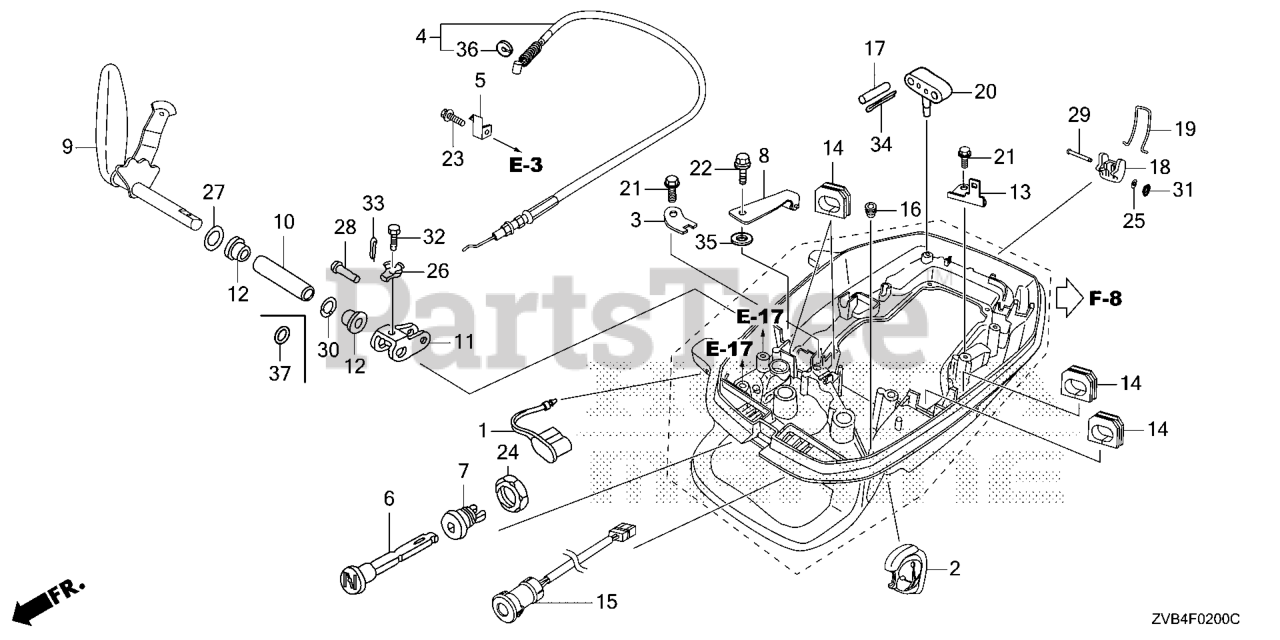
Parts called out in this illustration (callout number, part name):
2	GROMMET, THROTTLE CABLE
3	HOLDER, CABLE
4	CABLE COMP
5	BRACKET, CABLE
6	KNOB, CHOKE
7	GUIDE, CHOKE KNOB
8	SPRING, CLICK
9	SHAFT, SHIFT
9	SHAFT, SHIFT (NOT AVAILABLE)
10	COLLAR, SHIFT SHAFT
11	ARM, SHIFT
12	BUSH, SHAFT (NOT AVAILABLE)
13	BRACKET, CONNECTOR A
14	GROMMET, WIRE
15	LAMP ASSY., INDICATOR
16	GROMMET A, CASE (LOWER)
17	PIN, SHEAR
18	LEVER, FASTENER
19	WIRE, FASTENER (3.2)
20	HOLDER, PARTS
21	BOLT, FLANGE (6X14) (CT200)
22	BOLT, FLANGE (6X12) (CT200)
23	BOLT, FLANGE (6X12)
24	NUT, HEX. (16MM)
25	WASHER, PLAIN (5MM)
26	WASHER, TONGUED
27	WASHER, PLAIN (10MM)
28	PIN, HEX. (5X15)
29	PIN (5X47)
30	O-RING (9.8X2.4)
31	RING, STOPPER
32	BOLT, HEX. (5X16)
33	PIN, SPLIT (1.6)
34	PIN, SPLIT (3.0)
35	WASHER, PLAIN (6MM)
37	O-RING (6.8X1.9) (P7)
